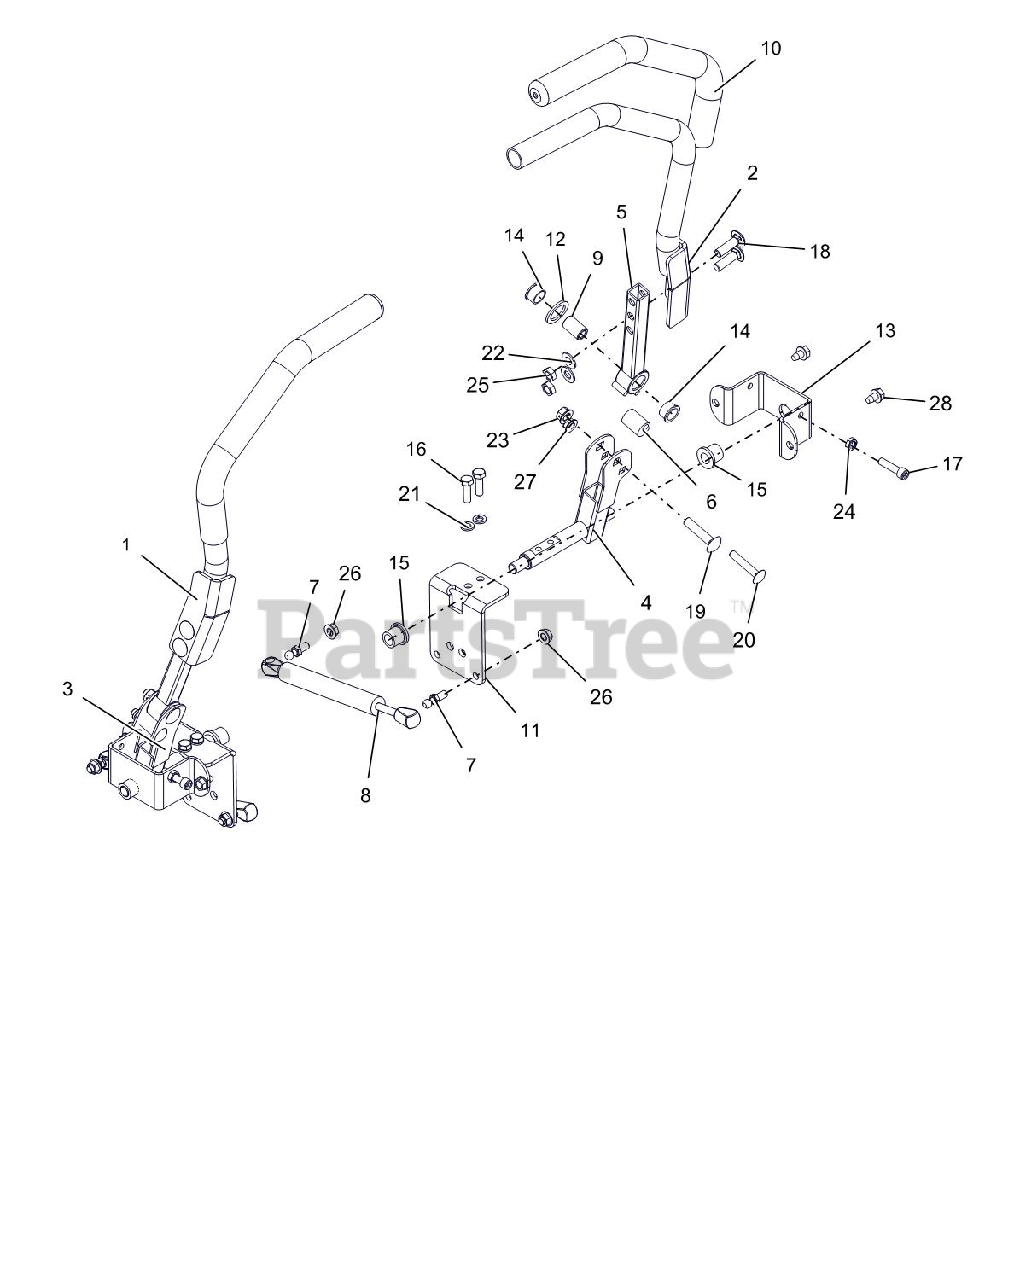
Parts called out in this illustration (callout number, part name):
1	WLDMT, STEERING HANDLE RH
2	WLDMT, STEERING HANDLE LH
3	WLDMT,STEERING ARM LOWER RIGHT
4	WLDMT,STEERING ARM LOWER LEFT
5	WLDMT, UPPER CONTROL ARM
6	BSHG,ECCEN .328X.750X1.01 PM
7	STUD- BALL
8	DAMPER, STABILUS
9	SPACER, .375X.625X.970 (PM)
10	GRIP, HANDLEBAR 15" FOAM
11	BRKT, STEEERING
12	WASHER, FRICTION .875X1.25X.10
13	BRKT, STEERING SUPPORT
14	BSHG-FLG, .625X.75X.450X.875
15	BSHG-FLG .515X.750X.745X1.00NY
16	BLT-HEX .31-18X1.00 GR8 YWZC
17	SHCS .312-18 X 1.25 GR8 YWZC
18	BLT,RHSSN .38-16X1.25 G5 BFP
19	BLT,RHSSN .38-16X1.75 G5 BFP
20	BLT,RHSSN .31-18X1.75 G5 BFP
21	@WSHR-LK .31X.078 REG YWZC
22	@WSHR-FL-STL.406X.812X.065 YWZ
23	NUT-LK-CTR-FLG .38-16 YWZC
24	NUT- JAM .312-18 YWZC
25	@NUT-LK-CTR-JAM .375-16 YWZC
26	@NUT-LK-TOP-FLG .31-18 YWZC
27	@NUT-LK-NYL-FLG .31-18 YWZC
28	@SCR-TAP .31-18X.50 HWH TR YWZ
